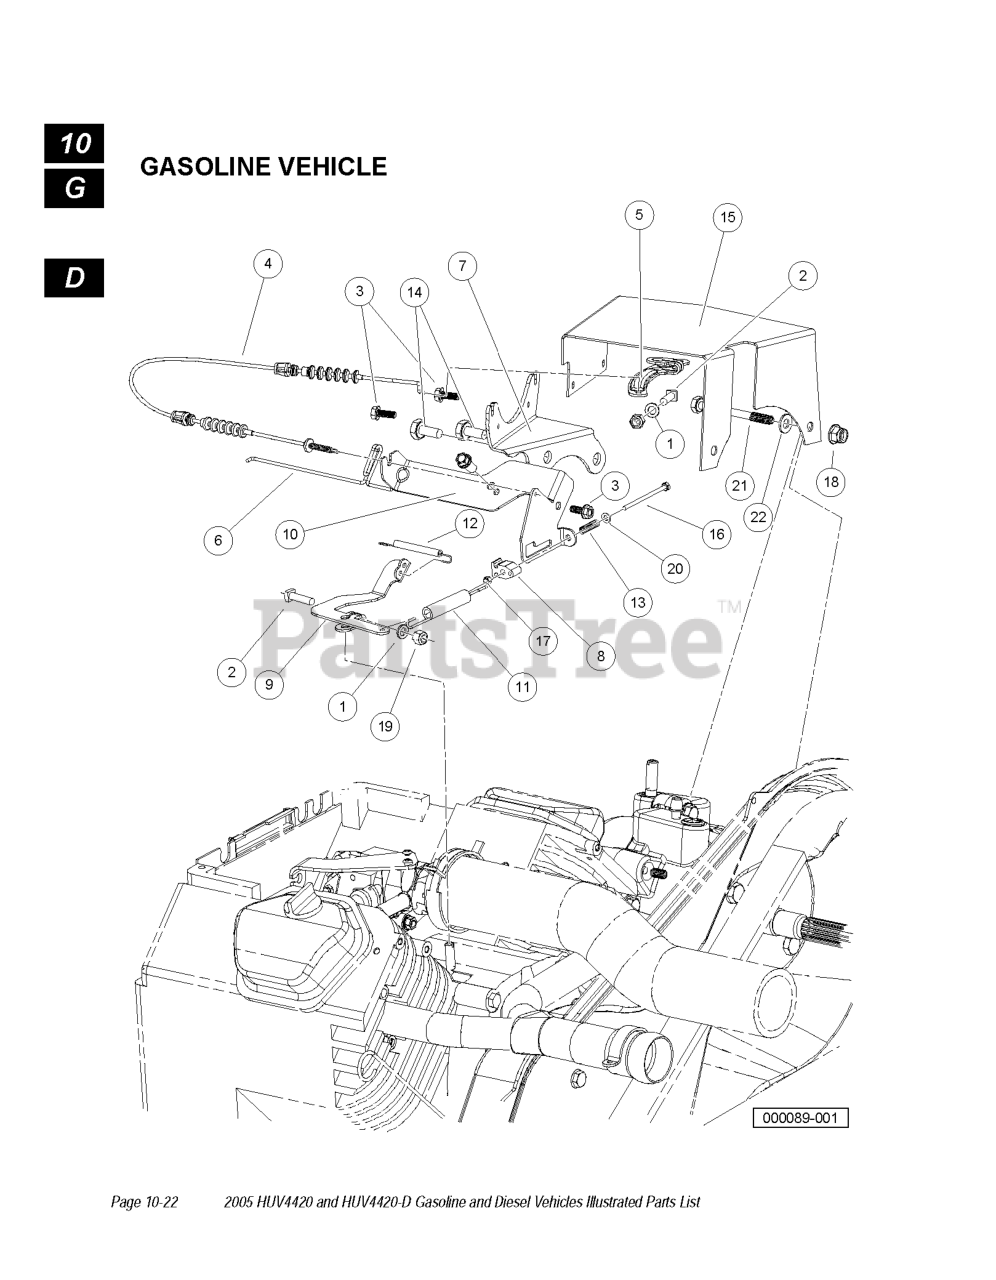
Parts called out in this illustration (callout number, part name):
2	SCREW, 1/4-20 X 1.00 SQ HEAD
3	SCREW, M6 X 16 TT HX FL HD
4	CABLE, GOVERNOR, GX620
5	BRACKET, GOVERNOR, ARM, TRANS
6	WIRE, GOVERNOR
7	BRACKET, GOVERNOR, TRANS CABLE
8	ADJUSTER, SPRING, IDLE
9	BRACKET, ARM, GOV, ENGINE
10	BRACKET, CABLE, GOV, ENGINE
11	SPRING, IDLE , GOVERNOR
12	SPRING, CARB
13	SPRING, COMPRESSION, ADJ, IDLE
14	BOLT, M10 X 1.5 X 20 LOCTITE
15	GUARD, GOVERNOR, GROUND SPEED
16	BOLT, M4X.7X60
17	NUT FLG, M4 X 0.7 MECH DEF
18	LOCK NUT, FLG M8 X 1.25 NYLON
19	LOCKNUT, 1/4-20 NYLON INSERT
20	WASHER, M4
21	BOLT, M8 X 1.25 X 80
22	WASHER, M8 HARD
